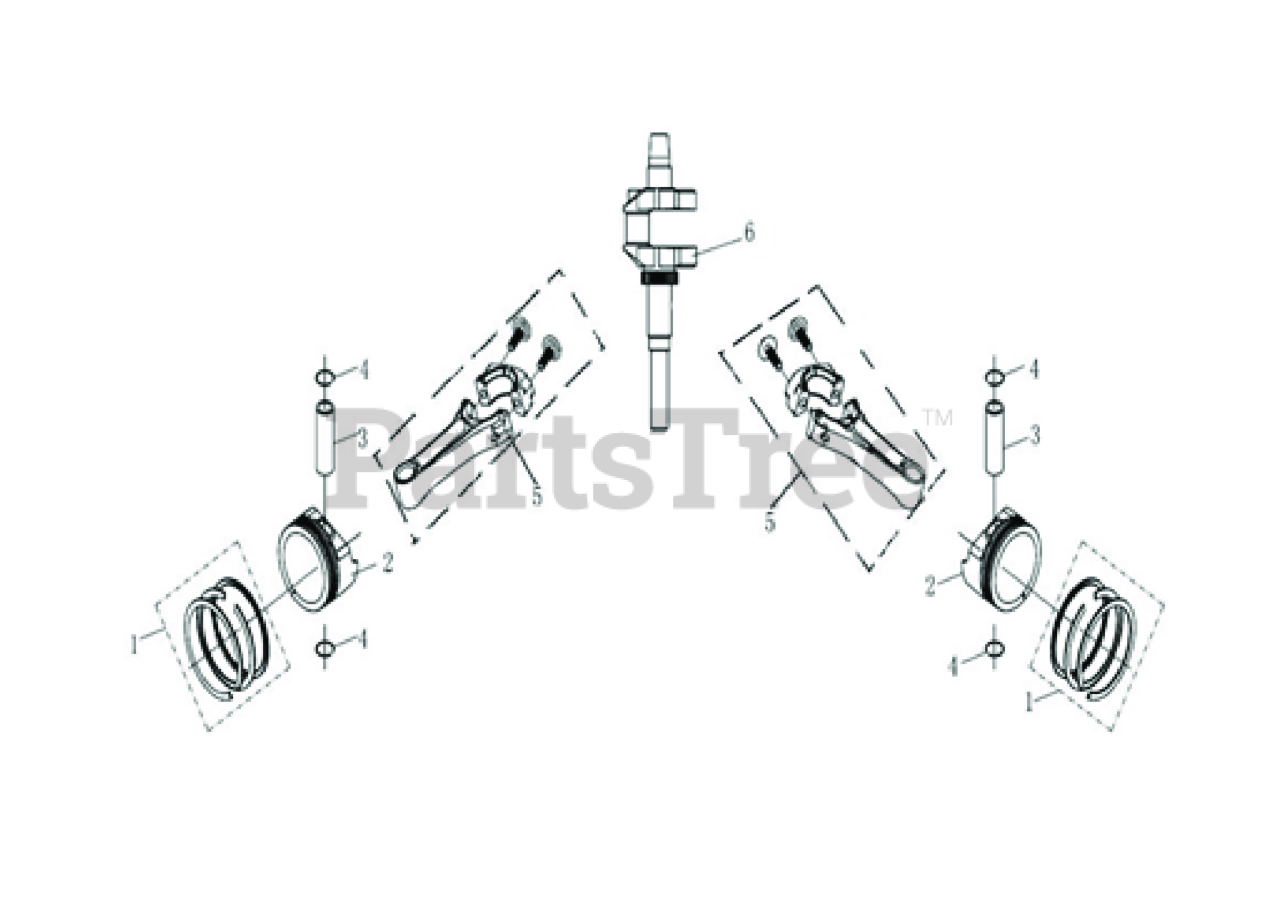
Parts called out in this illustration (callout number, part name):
1	Ring Set, SR708
2	Bushing, Anti-Scalp Wheel
3	Bushing, 1" ID Oilite
4	Circlip
5	Connecting Rod
6	REPLACED BY 48100-02
